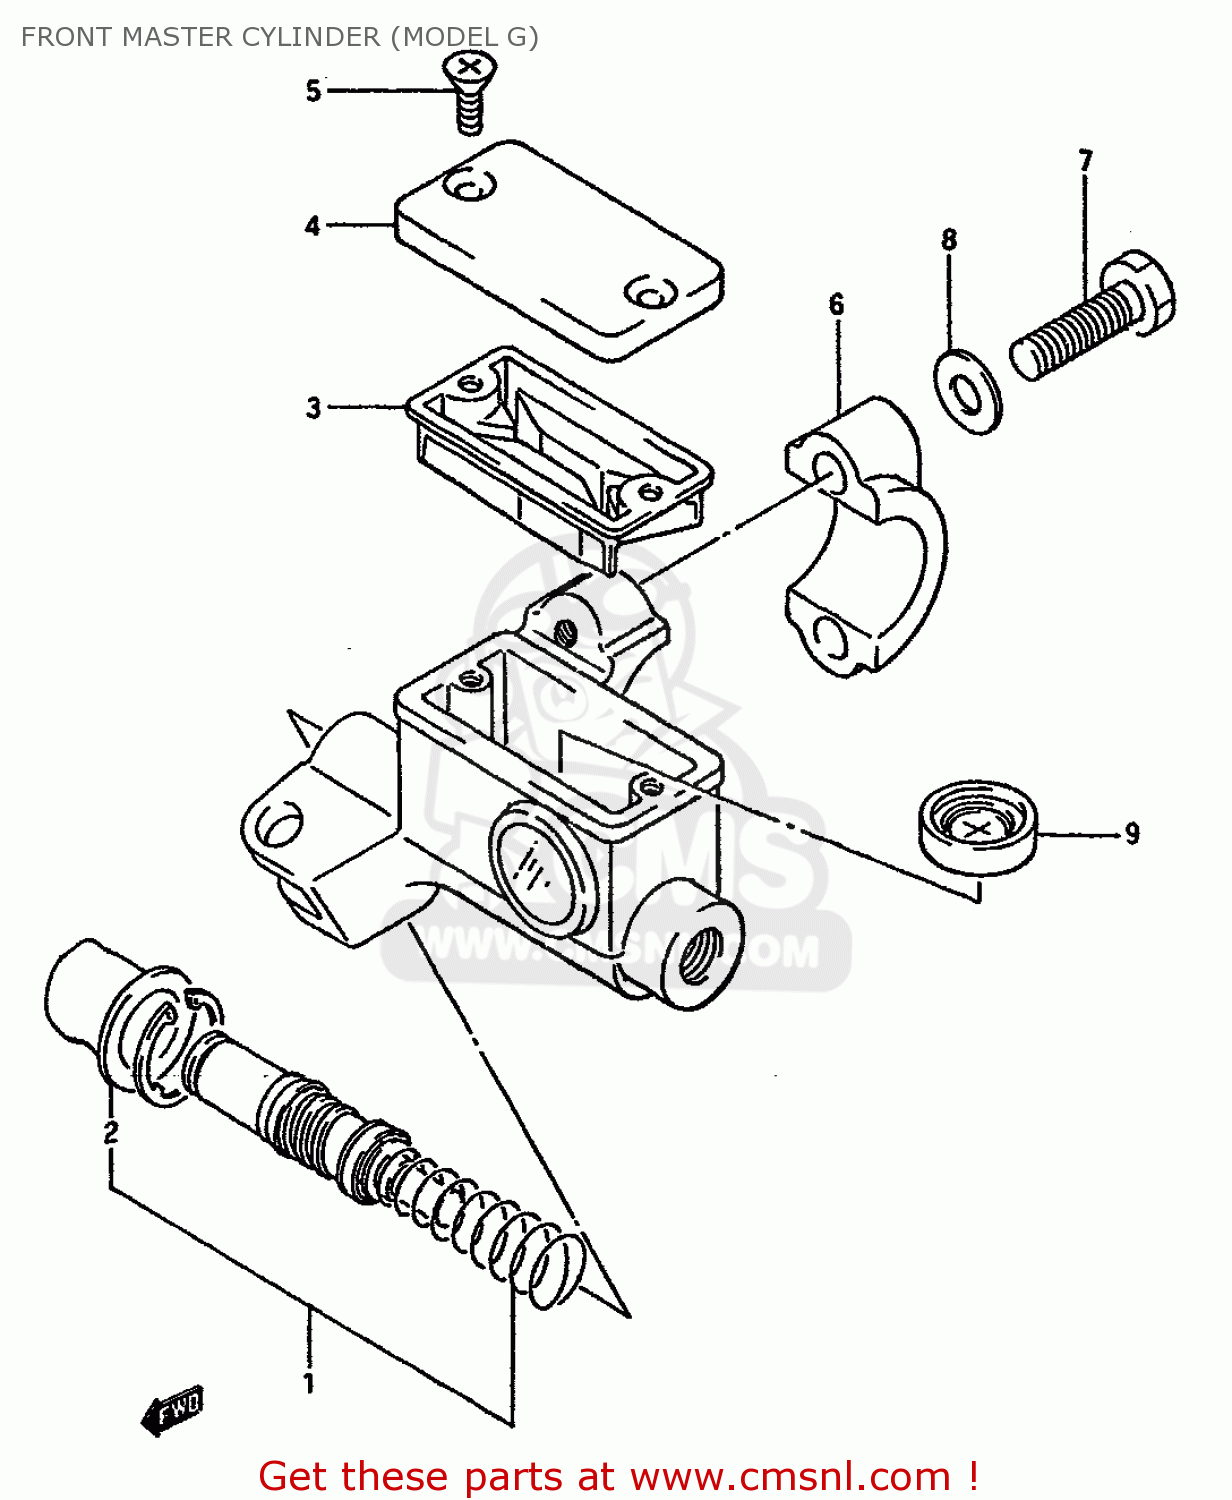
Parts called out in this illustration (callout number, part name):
1	PISTON/CUP SET,FR MASTER
2	BOOT
3	DIAPHRAGM
4	CAP
5	SCREW
6	HOLDER,MASTER CYLINDER
7	BOLT
8	WASHER
9	SEPARATOR
